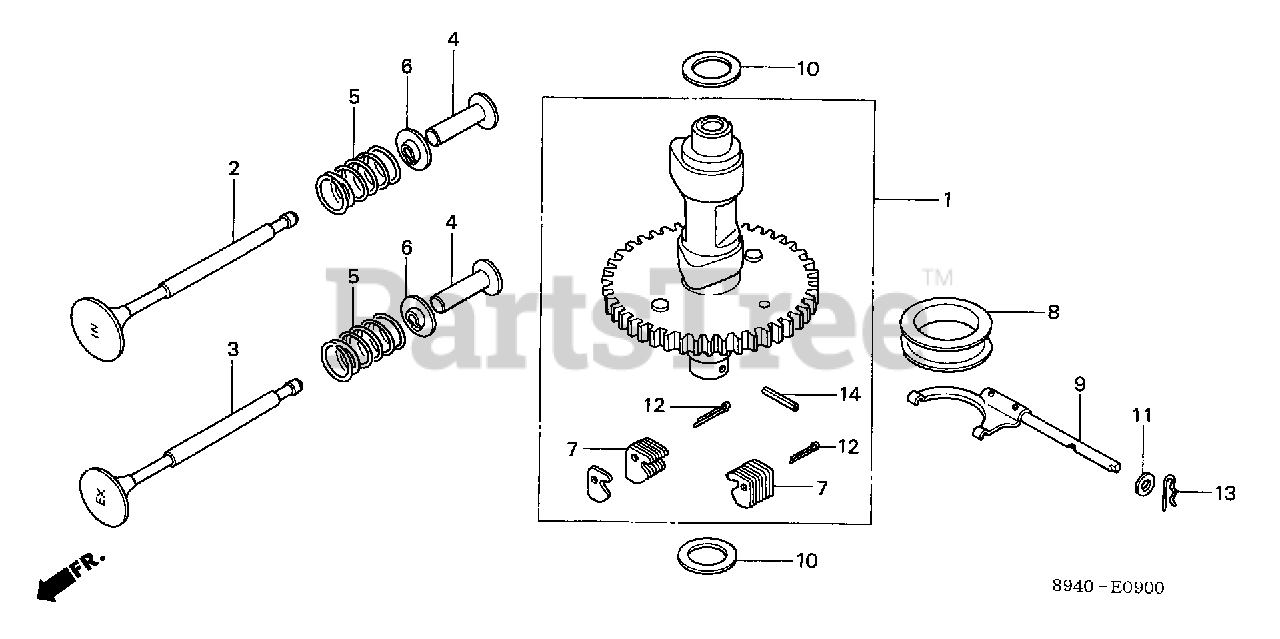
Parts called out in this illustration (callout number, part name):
1	CAMSHAFT ASSY.
2	VALVE, IN.
3	VALVE, EX.
4	LIFTER, VALVE (39.6MM)
4	LIFTER, VALVE (39.9MM)
5	SPRING, VALVE
6	RETAINER, VALVE SPRING
7	WEIGHT, GOVERNOR
8	SLIDER, GOVERNOR
9	SHAFT, GOVERNOR
10	WASHER, THRUST (18MM)
11	WASHER, PLAIN (6MM)
12	PIN, COTTER (3.0X45)
13	PIN, LOCK (8MM)
14	PIN, SPRING (2.5X16)
